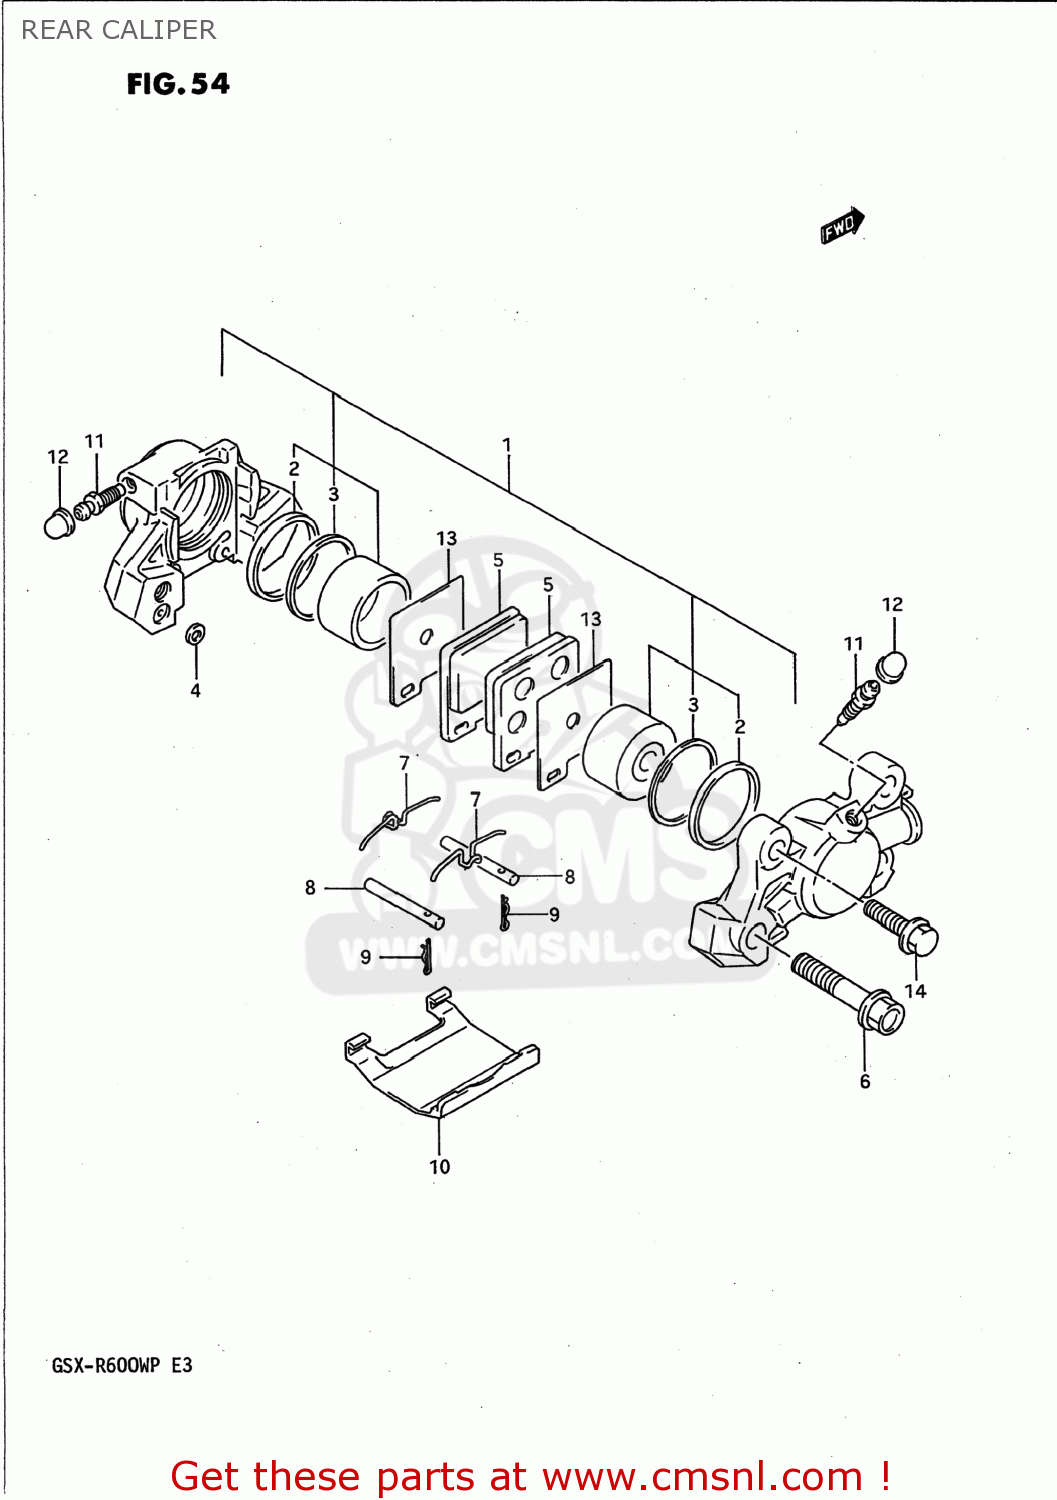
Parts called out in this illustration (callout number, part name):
1	PISTON SET
2	SEAL,PISTON
3	SEAL,WIPER
4	SEAL,JOINT
5	PAD,BRAKE
6	BOLT
7	SPRING
8	PIN,PAD
9	CLIP,PAD PIN
10	COVER
11	BLEEDER
12	CAP,BREATHER
13	SHIM,PAD
14	BOLT
